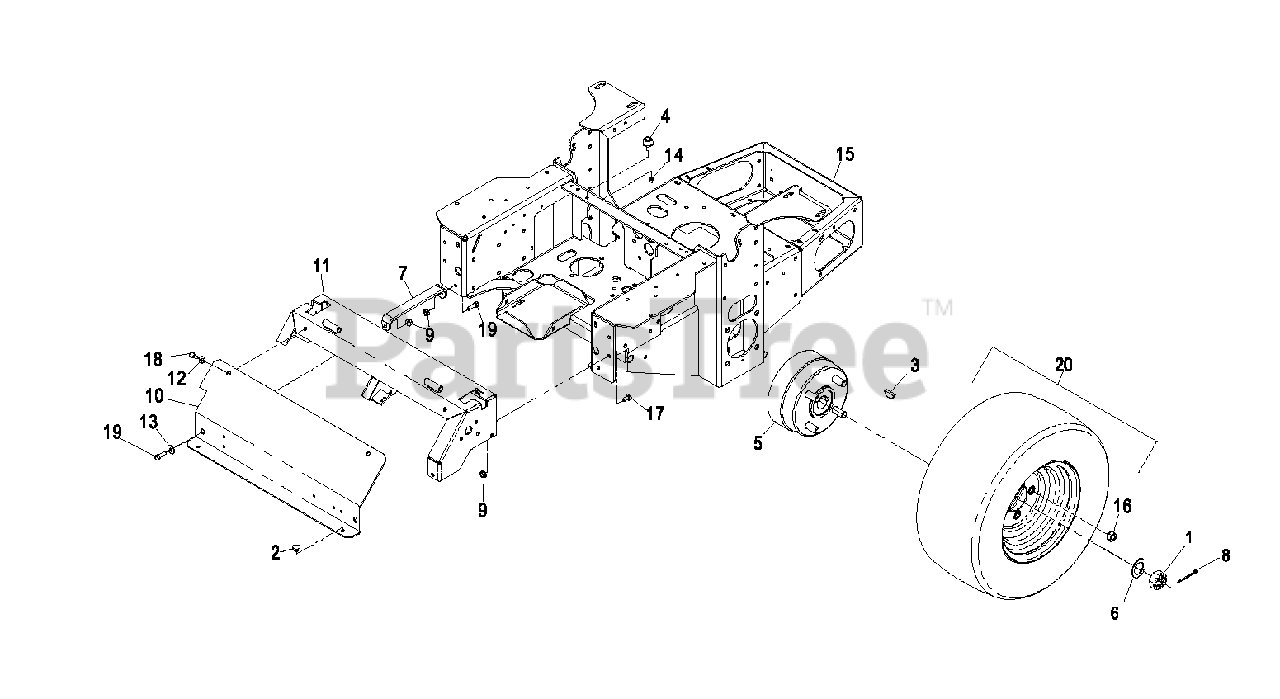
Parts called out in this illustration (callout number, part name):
3	KEY-WOODRUFF
5	WHEEL HUB ASM
5	STUD-WHEEL
6	WASHER-SPACER
7	BRACKET-PANEL, INSTRUMENT
8	PIN-COTTER
10	ASM,CONSOLE CT W/DECAL
11	ASM, CONSOLE W/DECALS
12	WASHER-PLAIN
13	WASHER-FLAT
15	WLD,MAINFRAME LCT
16	NUT-LUG
17	SCREW-HH
18	SCREW-HH
19	SCREW-HH
20	WHEEL AND TIRE ASM
